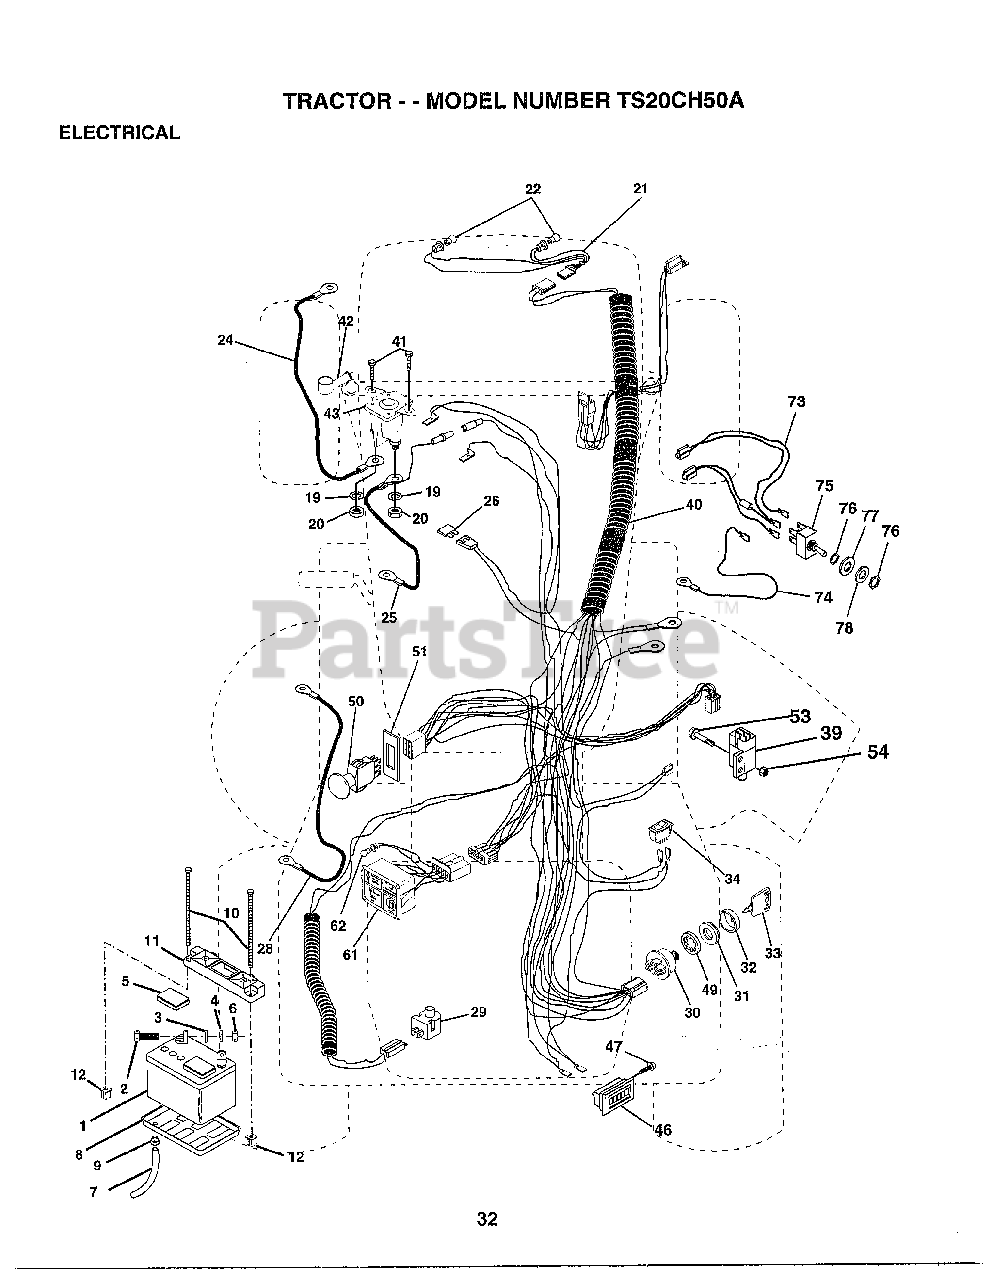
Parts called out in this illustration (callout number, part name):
2	BOLT LT
3	LOCKWASHER
4	WASHER
5	"CAP,BATTERY "
7	"DRAIN TU T, BATT"
8	"TRAY T, BATTERY"
9	HOSE CLAMP T
20	NUT
21	"HARNESS,LIGHT SOC"
22	HEADLAMP BULB
24	CABLE.BATY.22.RED
25	CABLE.BATRY.4GA.
26	FUSE HYT
28	CABLE.BATRY.4GA.
29	SWITCH SEAT
32	COVER KEY SWITCH
33	KEY MLD GEN DELTA
34	SWITCH LT
39	SWITCH INTERLOCKT
41	SCREW
46	HOUR METER T
47	SCREW
49	LOCKWASHER
51	RING RETAIN PTO
53	SCREW
54	"NUT,KEPS"
61	LIGHT.PKG.ASM.
62	BULB LIGHT T
73	HARNESS ASM LIFT
74	WIRE LIFT SWI T
78	WASHER
